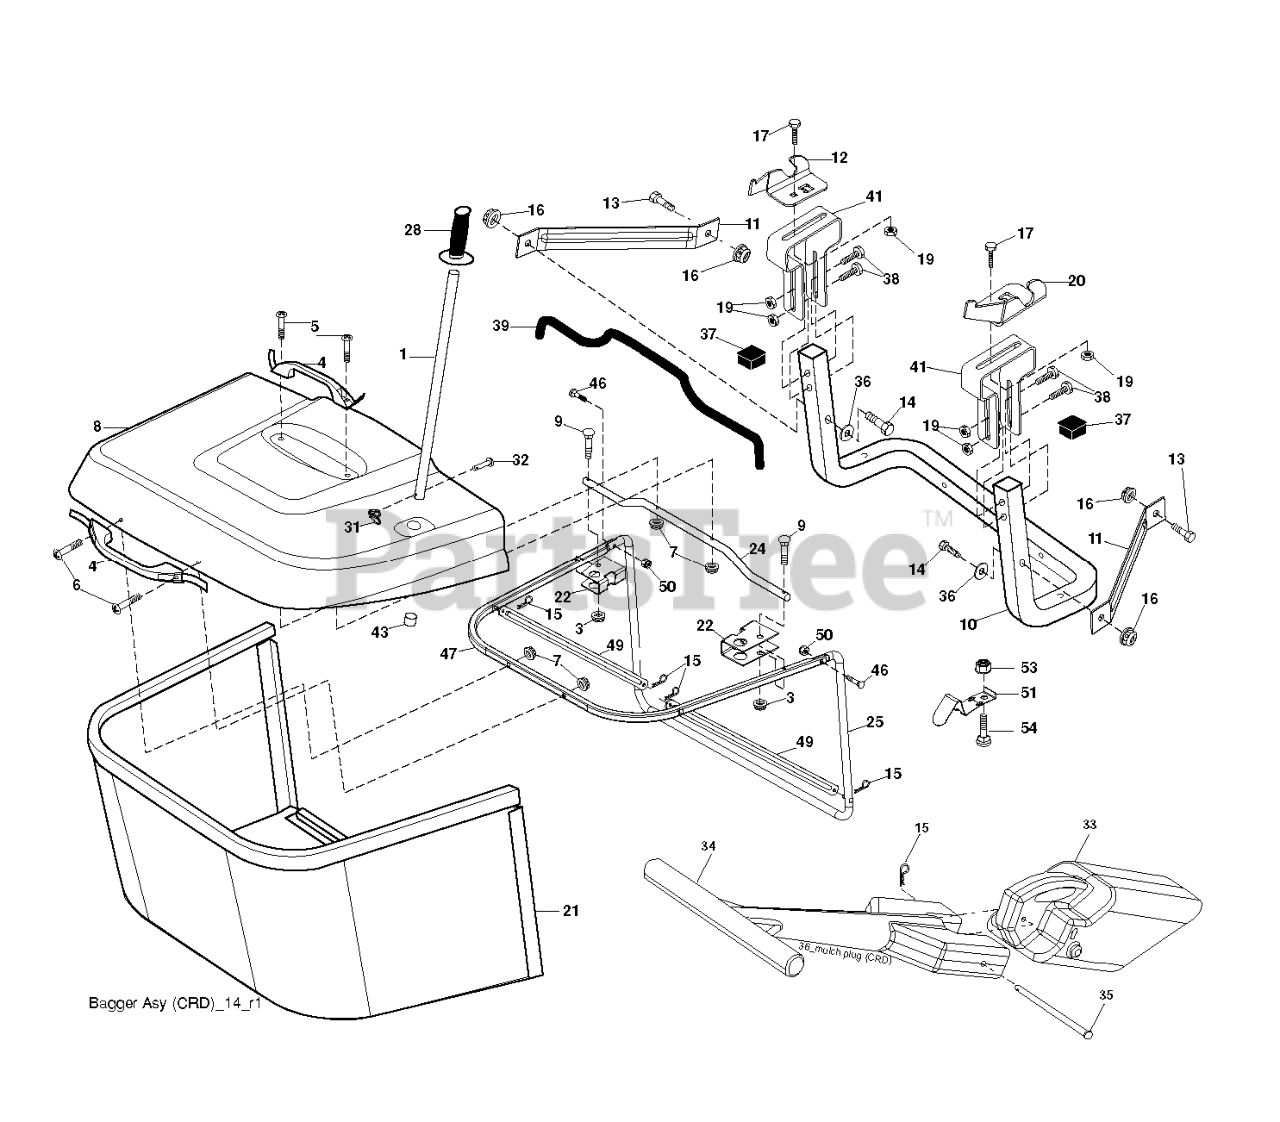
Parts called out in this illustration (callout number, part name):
1	TUBE HANDLE
3	NUT T
4	HANDLE.BAGGER.W/LVRS.BLK.CRD
5	SCREW.PAN.HEAD
6	REPL BY 532 75 00-29
8	COVER.PNT.BGR.CRD.WSLOTS.MS668
9	Bolt Carriage 1/4-20 x 2.25d x Gr.5
10	TUBE
11	BRACKET.SUPPORT.UPPER.BAG.CRD
12	BRKT PIVOT
14	BOLT-HEX EAK
15	RETAINER-SPRNG RB
16	NUT LOCK FLG 3/8-16 UNC
17	RP BOLT 5/16-18 X3/4 ZN/YEL GR
19	NUT LOCK HEX FLANGE 5/16-18
20	BRKT.PIVOT.RH.CRD
21	BAGGER.ASM.CRD.2007
22	BRKT.SIDE.BAG.CRD
24	TUBE.PIVOT.BAG.CRD.BLACK
25	PIPE
28	GRIP.HANDLE.BLACK
31	RETAINER CLIP
32	RIVET,DRILLED
33	PLUG.MULCHER.92 CRD
34	HANDLE.MULCHER.92.CRD (2 2)
36	WASHER
37	Plug Support Bagger CRD
38	BOLT.5/16-18X2.5
39	SEAL.BAGGER.CRD
41	BRKT.VERT.ADJ.BAGGER.CRD
43	PLUG, TUBING END
46	BOLT.CARRIAGE.5/16-18
47	PIPE
49	ROD
50	NUT.71038.31-18.HEX.NYLOCK
51	LATCH
53	NUT
54	BOLT
